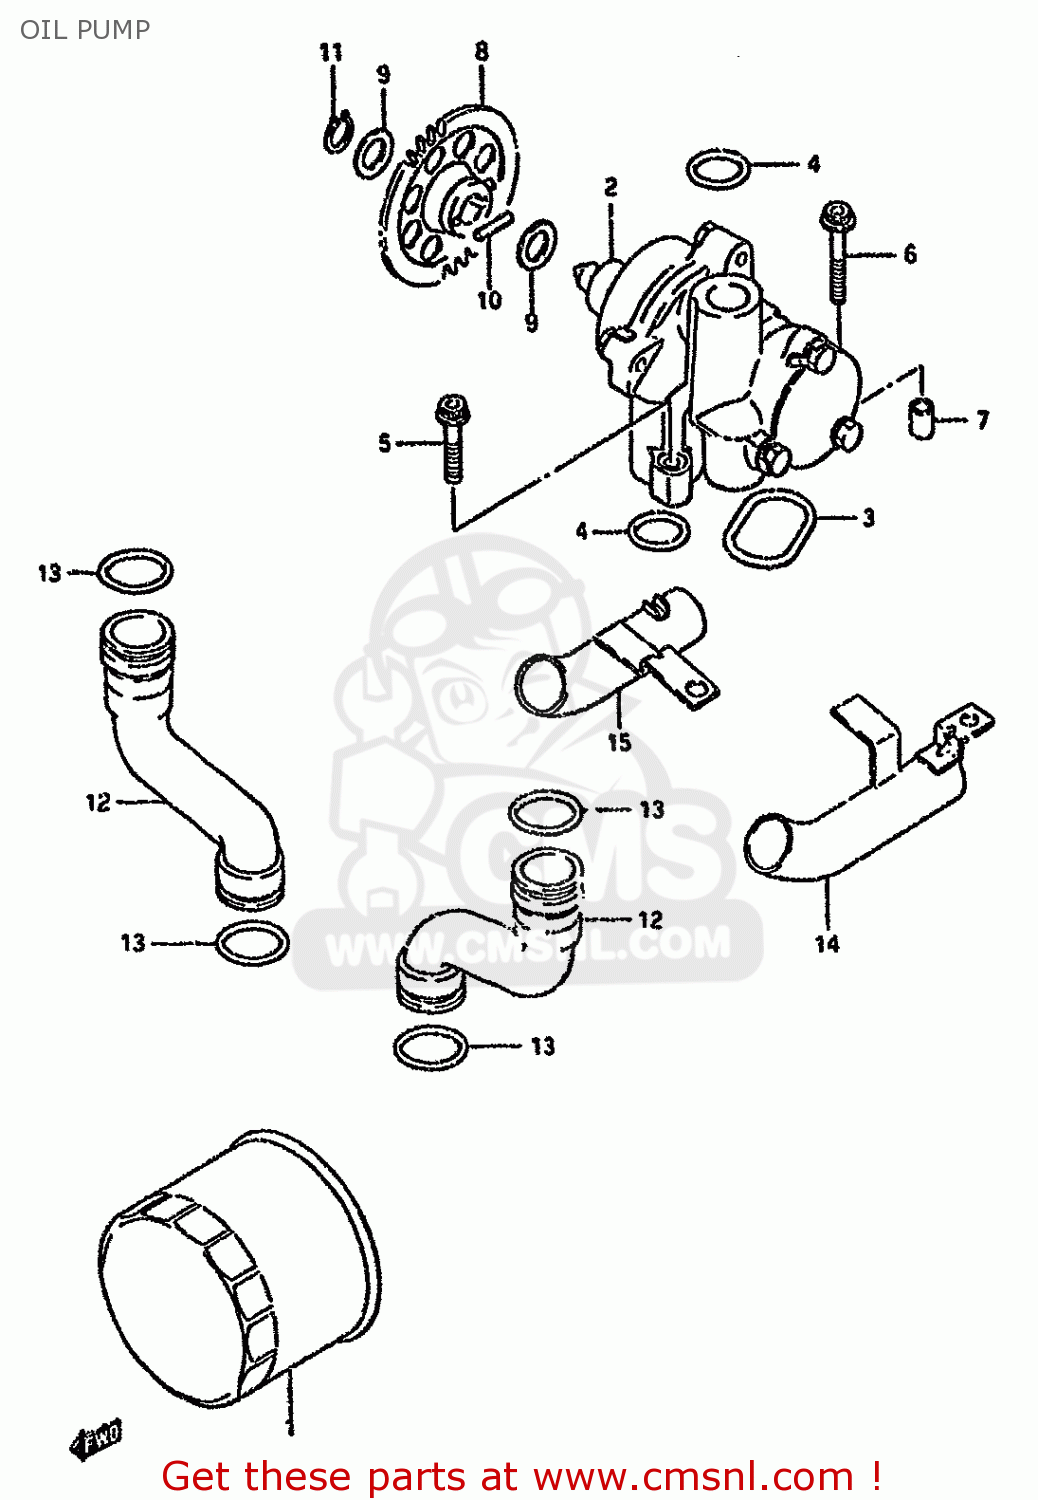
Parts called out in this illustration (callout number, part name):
1	FILTER ASSEMBLY,ENGINE OIL
2	PUMP ASSY,OIL
3	O RING,OIL PUMP
4	O RING(D:3.2,ID:17.8)
5	BOLT
6	BOLT
7	PIN
8	GEAR,OIL PUMP DRIVEN(NT:37)
9	SHIM
10	PIN(5X18)
11	CIRCLIP,12 MM
12	PIPE,OIL OUTLET
13	O RING(D:3.7,ID:21.7)
14	PIPE,OIL OUTLET UNDER,L
15	PIPE,OIL OUTLET UNDER,R
